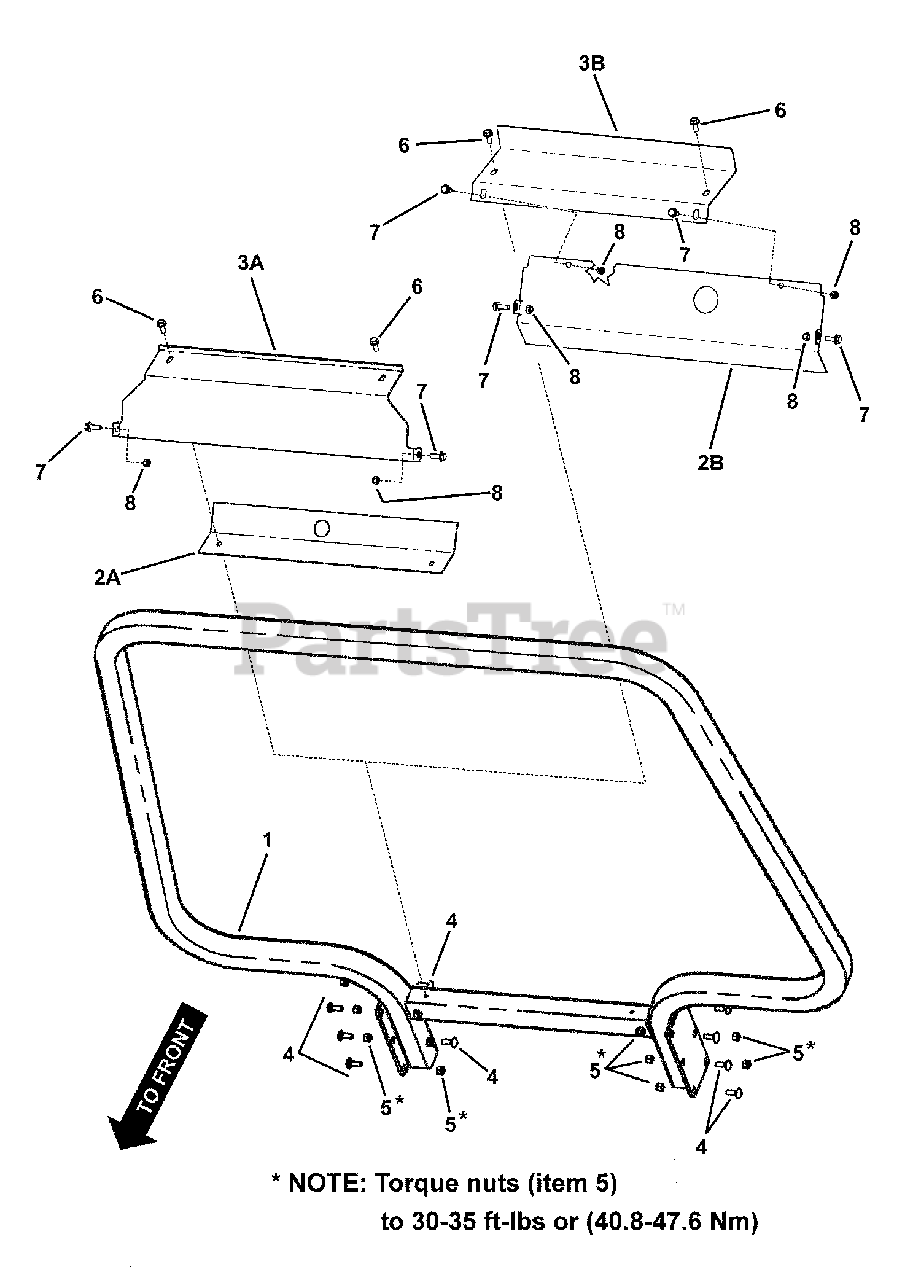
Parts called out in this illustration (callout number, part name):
1	WELDMENT, ROPS
2A	* HEAT SHIELD, Cab (UV-2)
2B	HEAT SHIELD (Red)
2B	HEAT SHIELD (Green)
3A	* SHIELD, Heat/Debris (Red)
3A	* SHIELD, Heat/Debris (Green)
3B	HEAT SHIELD, Top (Red)
3B	HEAT SHIELD, Top (Green)
4	BOLT, 3/8-16 x 1" Square Neck Carriage, GR 5
5	NUT, 3/8-16 Hex Nyloc
6	SCREW, 5/16-18 x 3/4" Hex Washer Self-Tap
7	BOLT, 5/16-18 x 7/8" Hex Flange Lock
8	NUT, 5/16-18 Hex Nyloc
